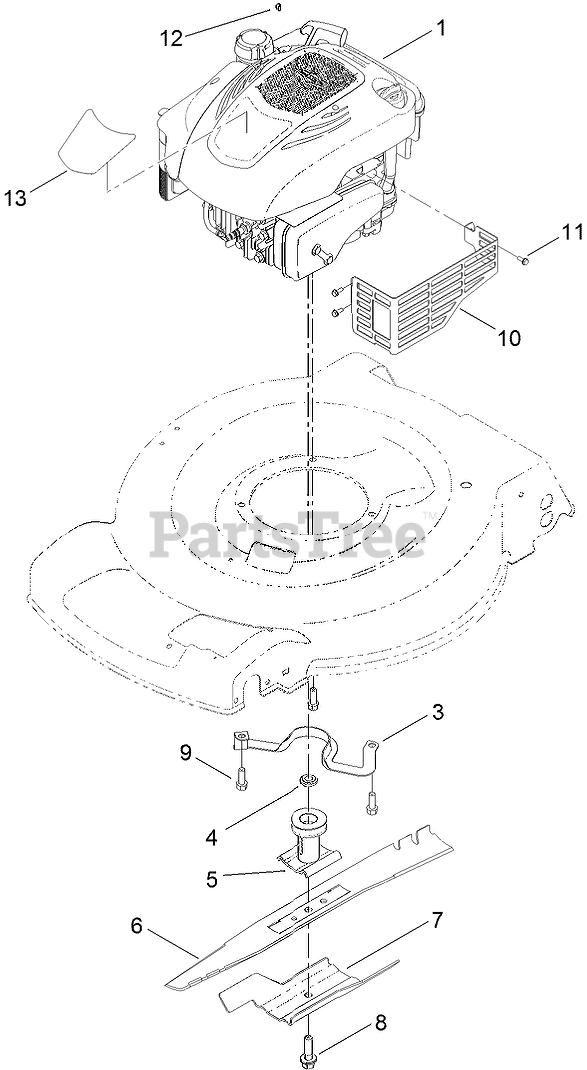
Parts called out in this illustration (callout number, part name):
3	Guide-Belt
4	Spacer-Driver
5	DRIVER-BLADE
6	BLADE
7	Accelerator-Blade
8	BOLT-BLADE
9	SCREW-TAPTITE
10	SHIELD-MUFFLER
11	SCREW-TAPTITE
12	STOP-ROPE
13	DECAL-SHROUD
